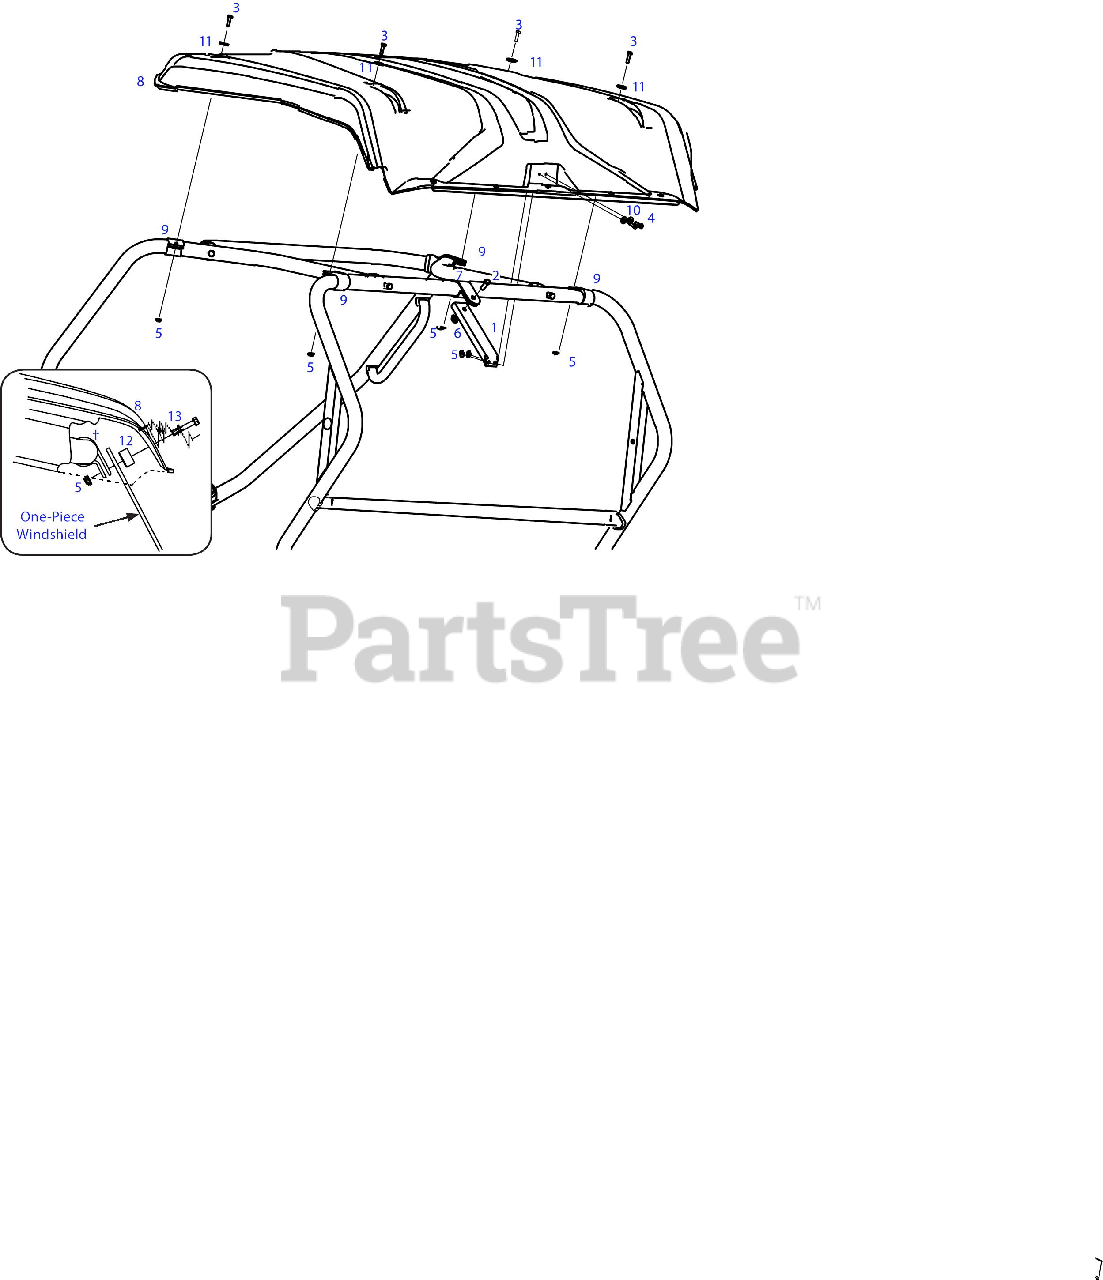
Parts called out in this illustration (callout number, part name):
1	Canopy Support Bracket
2	Screw 3/8-16 X 1 Gr5
3	Screw 1/4-20 X1.00 Gr5
4	Screw 1/4-20X.75 Gr5
5	Flange Lock Nut
10	Flat Washer .28 Id X .74 Od X .063
11	Flat Washer .275 X 1.00 X .103
13	Hex Flange Bolt 1/4-20 X 1.5
